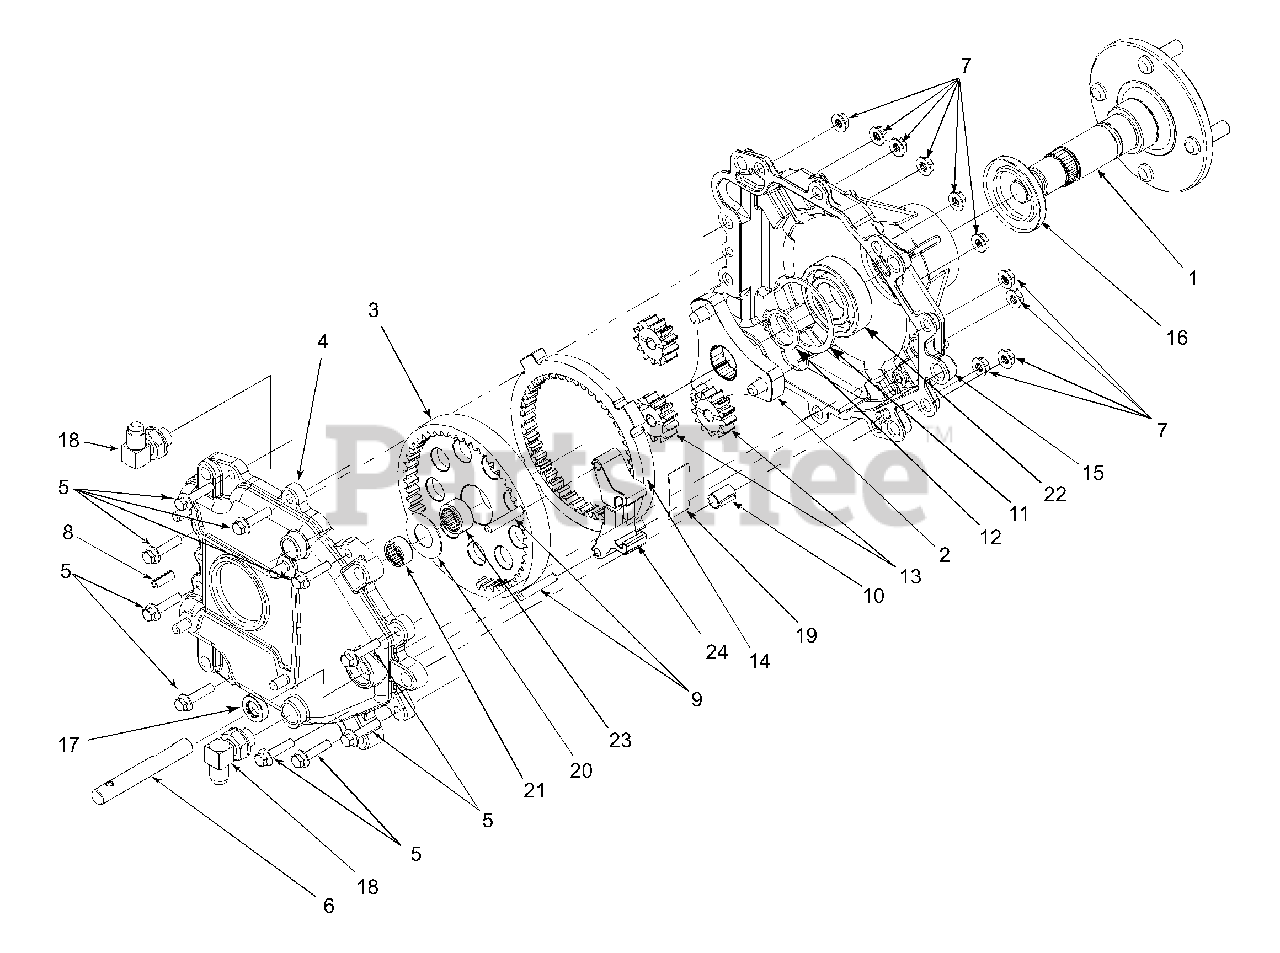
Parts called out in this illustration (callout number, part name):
1	Drive Ass'y Complete
2	Carrier Assembly, Output
3	Gear Assembly, 51T Internal & 20T
4	Housing Ass'y
5	Hex Washer Screw 1/4-20 x 1-1/8
7	Hex Flange Lock Nut 1/4-20
10	Bushing
11	Inverted Retaining Ring
13	Spur Gear 13T
14	Ring Gear 46T
15	Axle Outer Housing
16	Oil Seal
18	Elbow Fitting
19	Brake Shoe Spring
20	Shim Washer .76 x 1.5 x .030
21	Needle Bearing
22	Ball Bearing
23	Needle Bearing
